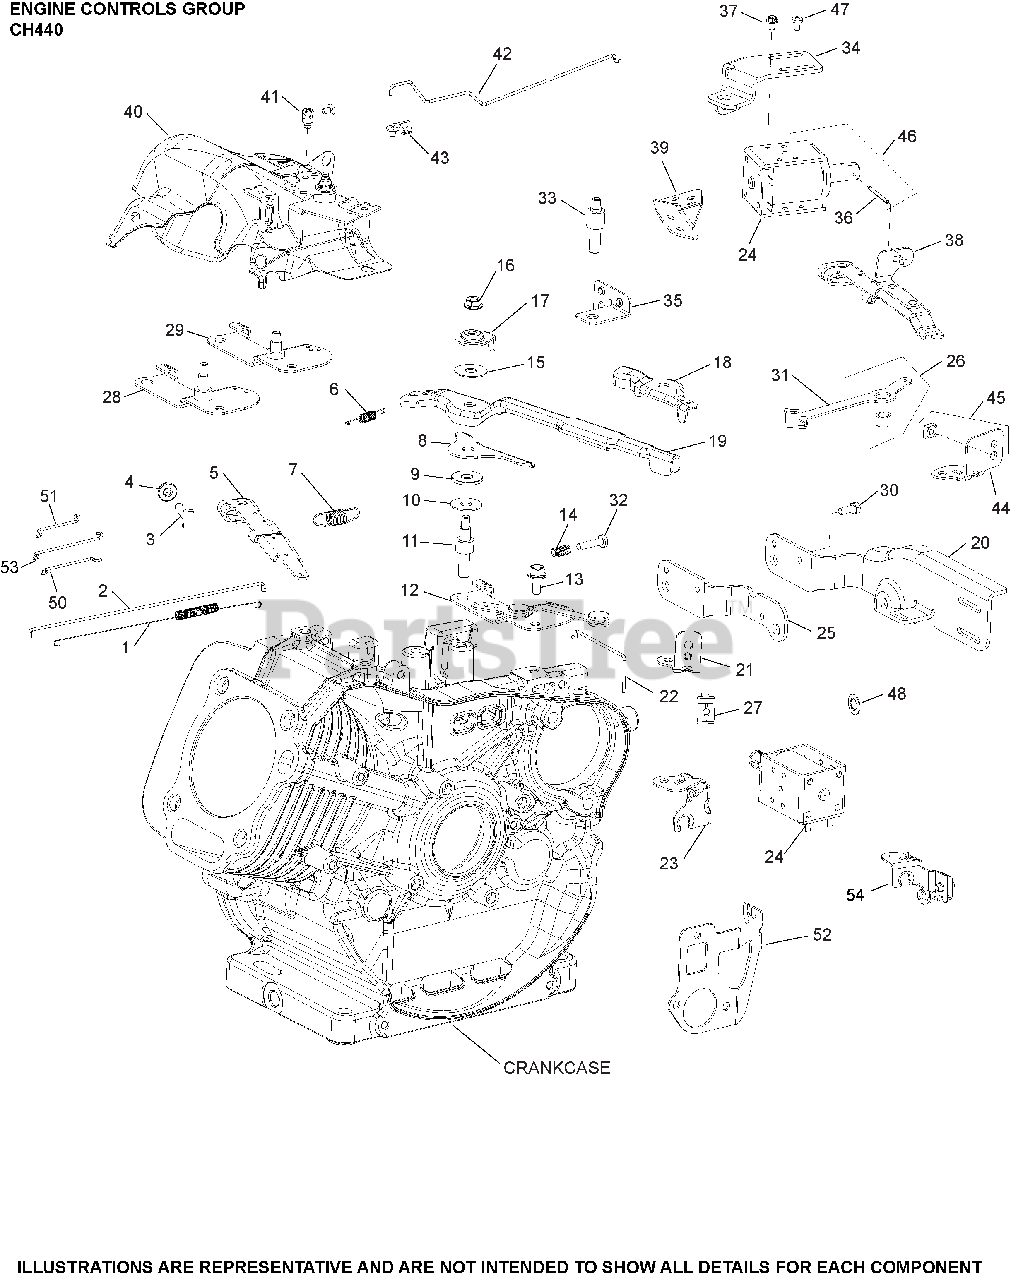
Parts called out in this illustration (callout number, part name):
1	SPRING, LINKAGE
2	LINKAGE, GOVERNOR
3	SCREW, RECTANGLE HEAD (M6)
4	NUT, HEX FLANGE (M6) - USE 14 100 16-S
5	KIT, GOVERNOR LEVER
6	SPRING, THROTTLE RETURN
7	SPRING, GOVERNOR
9	WASHER, NYLON CONTROL LEVER
10	WASHER, FLAT
11	STUD, CONTROL LEVER
12	BRACKET, CONTROL ASSEMBLY
13	SCREW, HEX FLANGE (M6)-USE 25 086 433-S
14	SPRING, COMPRESSION
15	WASHER, SPRING
16	NUT, HEX FLANGE LOCK (M6)
17	WASHER, CONTROL LEVER
19	CONTROL LEVER ASSEMBLY
27	CLAMP, CABLE
30	SCREW, HEX/PHILLIPS M5
32	SCREW, SPEED ADJUSTING (CKY)
39	BRACKET, BOWDEN CABLE ASSY
